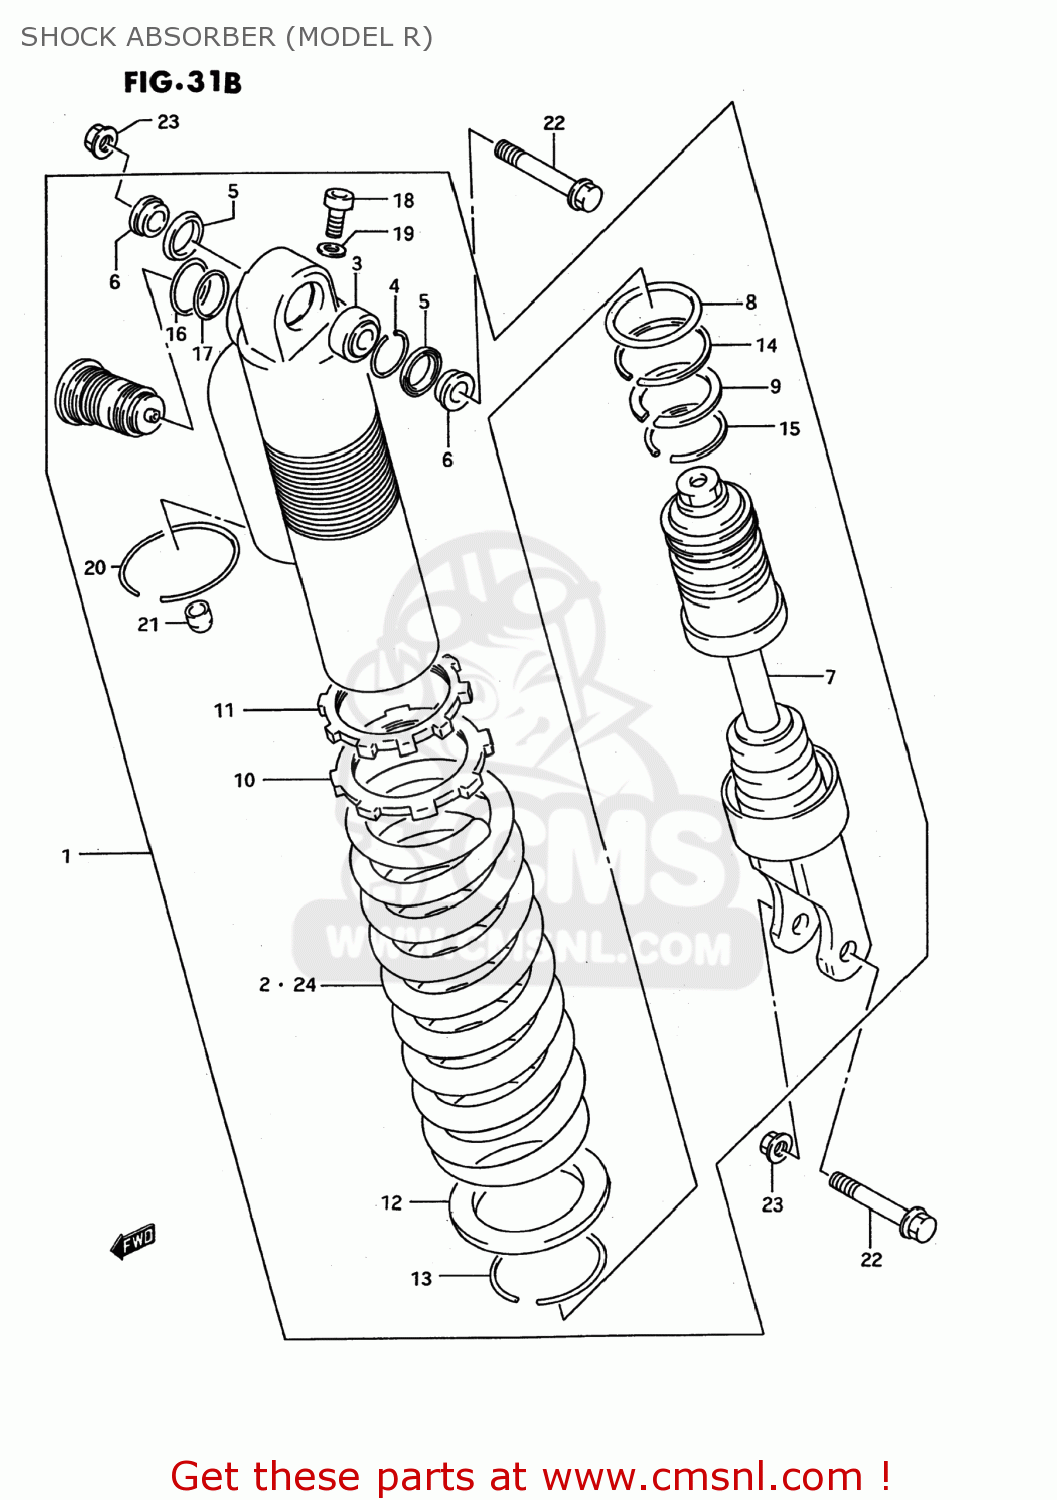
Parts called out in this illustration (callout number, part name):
1	ABSORBER ASSEMBLY,REAR SHOCK
2	SPRING
3	BEARING,RR CUSHION LEVER RR
4	RING,STOPPER
5	SEAL,DUST
6	COLLAR
7	ROD,PISTON
8	O RING
9	STOPPER
10	GUIDE,SPRING
11	NUT
12	SEAT,SPRING
13	RING,STOPPER
14	RING,STOPPER
15	RING,STOPPER
16	O RING
17	O RING,CTR BOLT UPR
18	BOLT,REAR SHOCK ABSORBER
19	GASKET,DRAIN,PLUG (NAS)
20	RING,STOPPER
21	CAP
22	BOLT,RR SHOCK ABSORBER
23	NUT
24	SPRING
